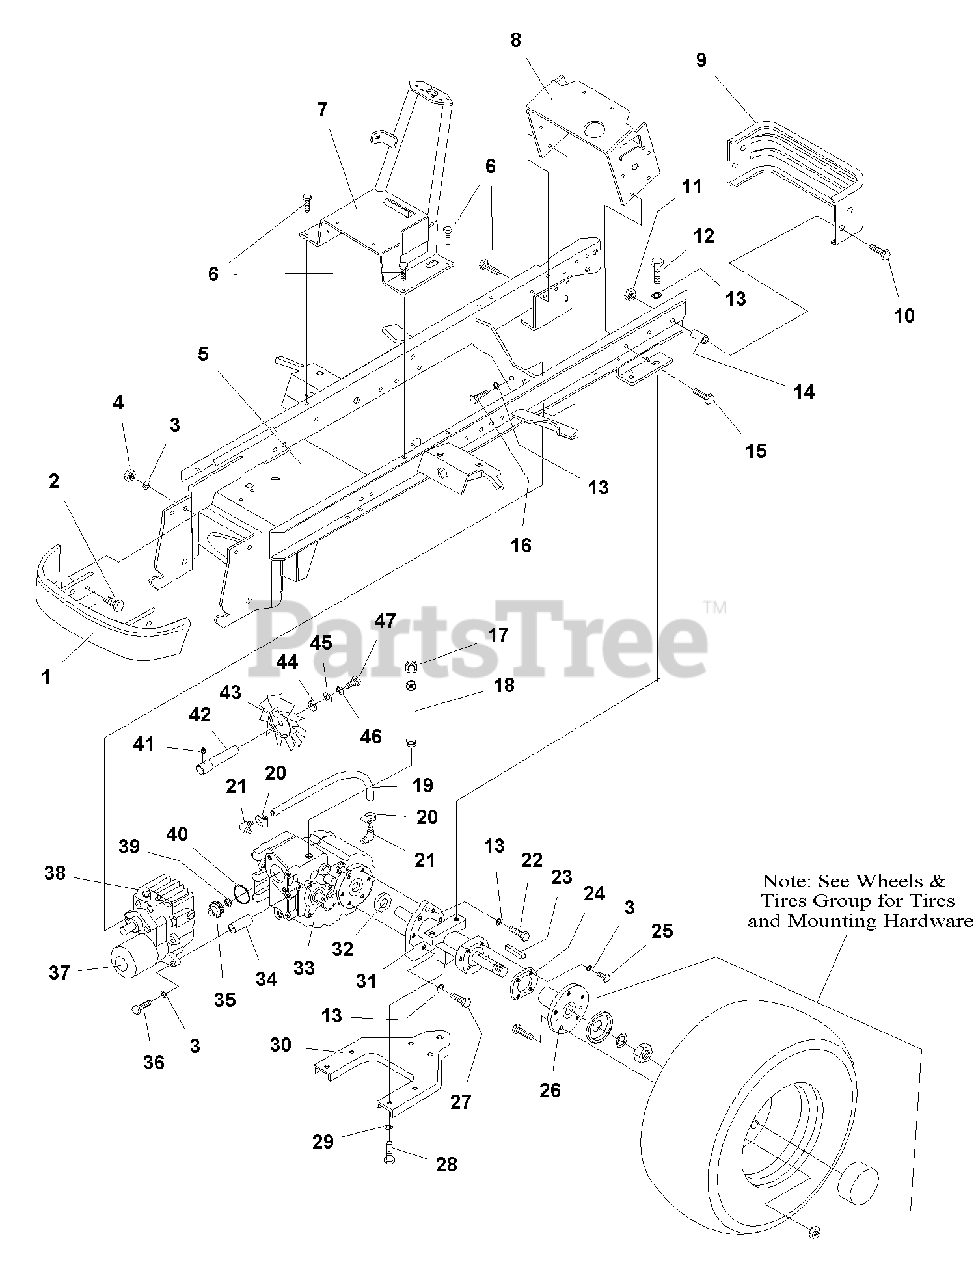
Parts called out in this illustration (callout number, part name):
1	FRONT BUMPER ASSEMBLY
2	CARRIAGE BOLT, 3/8-16 x 1-1/4
3	LOCKWASHER, 3/8
4	NUT, Hex, Full, 3/8-16
5	FRAME ASSEMBLY
6	CAPSCREW, Hex Head, Taptite, 5/16-18 x 3/4
7	TOWER ASSEMBLY, Steering
8	SUPPORT, Seat Deck
9	REAR BUMPER ASSEMBLY
10	CARRIAGE BOLT, (Short Neck) 5/16-18 x 2
11	NUT, Flange Lock, 5/16-18
12	CAPSCREW, Hex Head, 1/2-13 x 1-1/2
13	LOCKWASHER, 1/2
14	SPACER, RR Bumper
15	CAPSCREW, Taptite, 5/16-18 x .62
16	CAPSCREW, Hex Head, 1/2-13 x 1-1/4
17	CAP, Oil Fill
18	TUBE, Oil Fill
19	HOSE, Fluid Level
20	CLAMP, SAE #6
21	FITTING, Elbow
22	CAPSCREW, Hex Head, 1/2-13 x 1-1/2
23	KEY, 5/16 x 5/16 x 2-1/2
24	PLATE, Bearing Retainer
25	CAPSCREW, Hex Head, 3/8-16 x 5/8
26	HUB ASSEMBLY, Rear (Includes Studs)
27	CAPSCREW, Hex Head, 1/2-13 x 2
28	CAPSCREW, 5/8-11 x 1-1/4
29	LOCKWASHER, 5/16
31	PEERLESS HOUSING ASSEMBLY, Axle (See Axle Housing Service Parts )
32	SPACER, Axle
33	**TRANSAXLE, 2 Speed (See Transaxle Service Parts )
34	SPACER, Mounting
35	GEAR, Bevel
36	CAPSCREW, Hex Head., 3/8-16 x 4
37	FILTER, Oil
38	***HYDROSTATIC PUMP
39	RING, Retaining #62
41	SET SCREW, 1/4-20 x 5/16
42	SHAFT & HUB, Fan
44	WASHER, 1/4
45	LOCKWASHER, Dished, 1/4
46	LOCKWASHER, 1/4
47	CAPSCREW, 1/4-20 x 7/8
